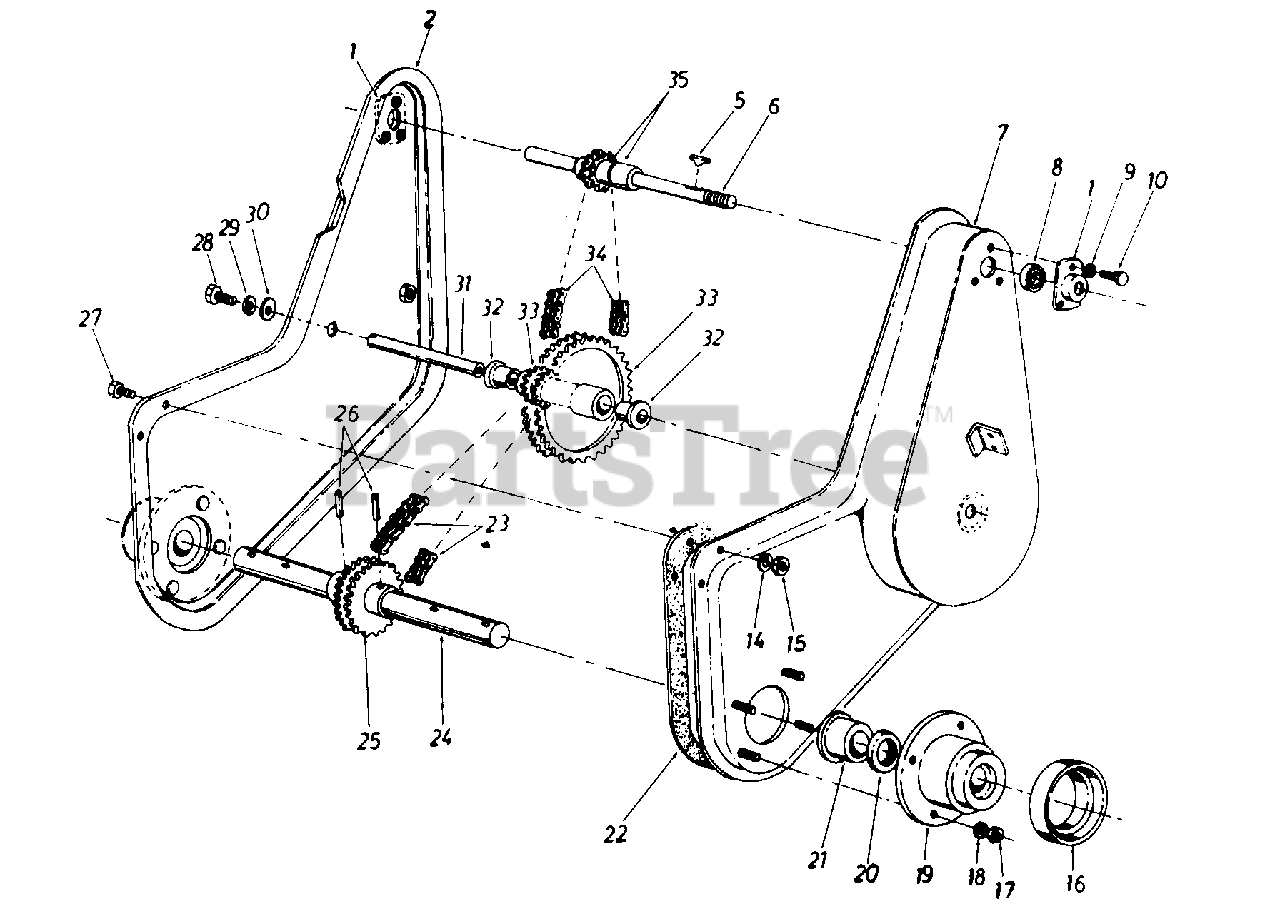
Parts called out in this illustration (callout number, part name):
1	Bearing Housing 1.375" Dia.
2	Housing Assembly R.H.
5	#6 Hi-Pro Key 5/32" x .62" Lg.
6	Input Shaft Assembly
9	L-Wash. 1/4" I.D.
10	Hex Bolt 1/4 20 x .62" Lg.
14	L-Wash. 1/4" I.D.
15	Hex Cent. L-Nut 1/4-20 Thd.
16	Dust Cap Cover
17	Hex Cent. L-Nut 5/16-18 Thd.
18	L-Wash. 5/16" I.D.
19	Cast Bearing Housing
20	Oil Seal
21	Flange Bearing 1.25" I.D. x 1.75" 0 D.
22	Gasket
23	Roller Chain #40-2 x 34.0" Lg.
24	Tine Shaft
25	Double Sprocket T24-2 Teeth 1/2" Pitch
26	Spiral Pin 3/8" Dia. x 2.00" Lg.
27	Hex Bolt 1/4-20 x .62" Lg.
28	Hex Bolt 5/16-18 x .75" Lg.
29	L-Wash. 5/16" I.D.
30	Fl-Wash. 5.16" I.D.
31	Sprocket Shaft
32	Flange Bearing .62" I.D. x .75" O.D.
33	Double Sprocket Assembly
34	Roller Chain #35-2 x 36.75" Lg.
35	Spacer 5/8" I.D. x 7/8" O.D.
